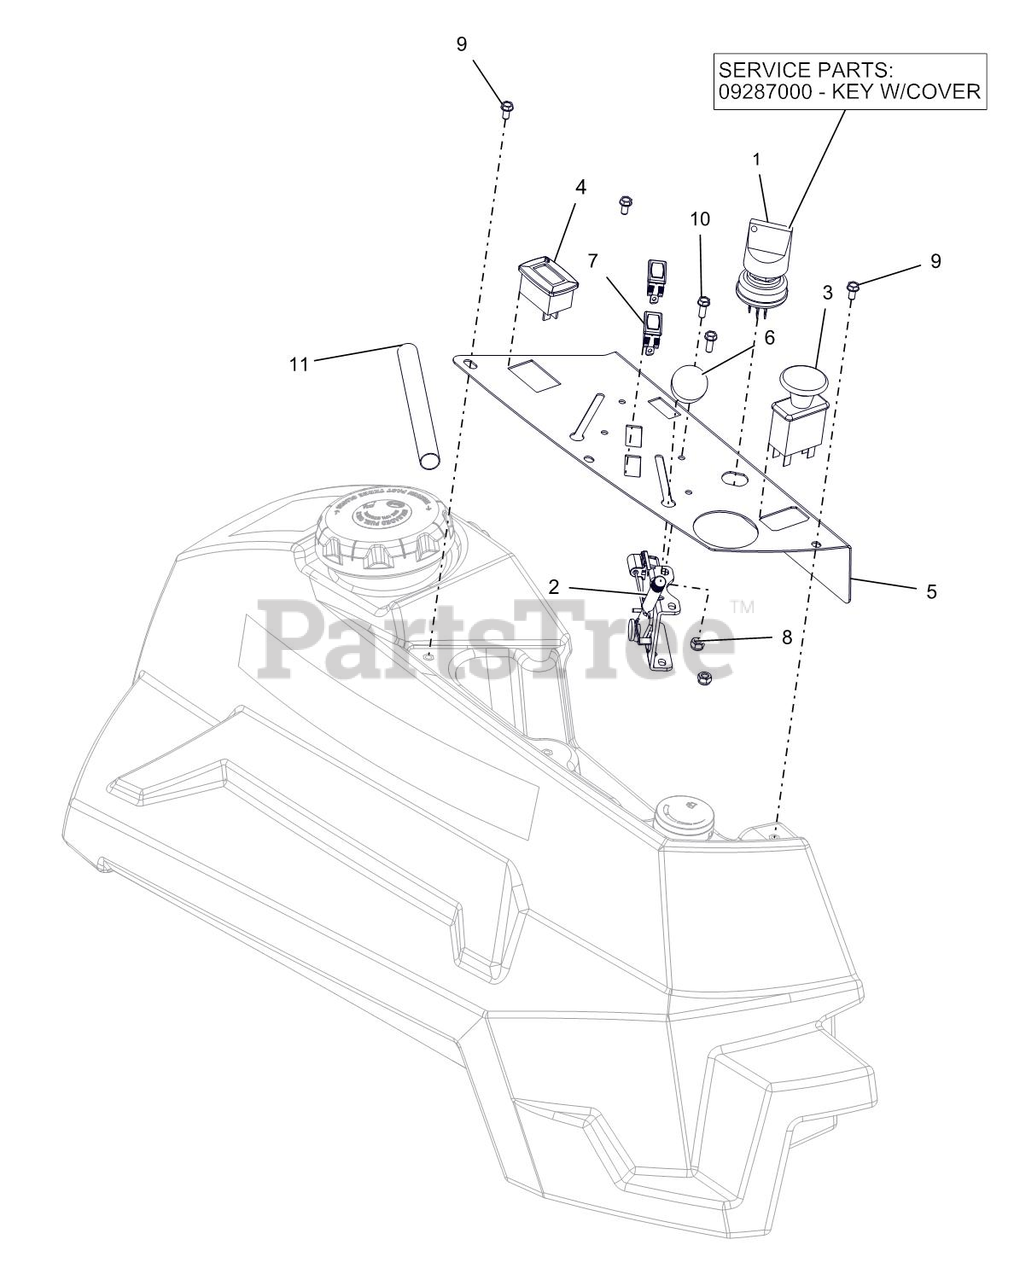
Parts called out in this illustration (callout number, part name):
1	KEY, W/ SHIELD
1	SWITCH, IGNITION
2	CABLE, PRO-CTRL 35.50"
3	SWITCH, CLUTCH
4	METER, HOUR W/MAINTENANCE
5	PT400 CONTROL PANEL - RED
6	KNOB-CONTROL-BLACK .38-16X.50
7	LIGHT,INDICATOR
8	@NUT-LK-NYL 10-24 W/INSRT YWZC
9	SCR-MCH 10-24X.38 HWHSTAINLESS
10	@SCR-MCH 10-24X.50 HWH YWZC
11	SLEEVE, THERMAL 6"
